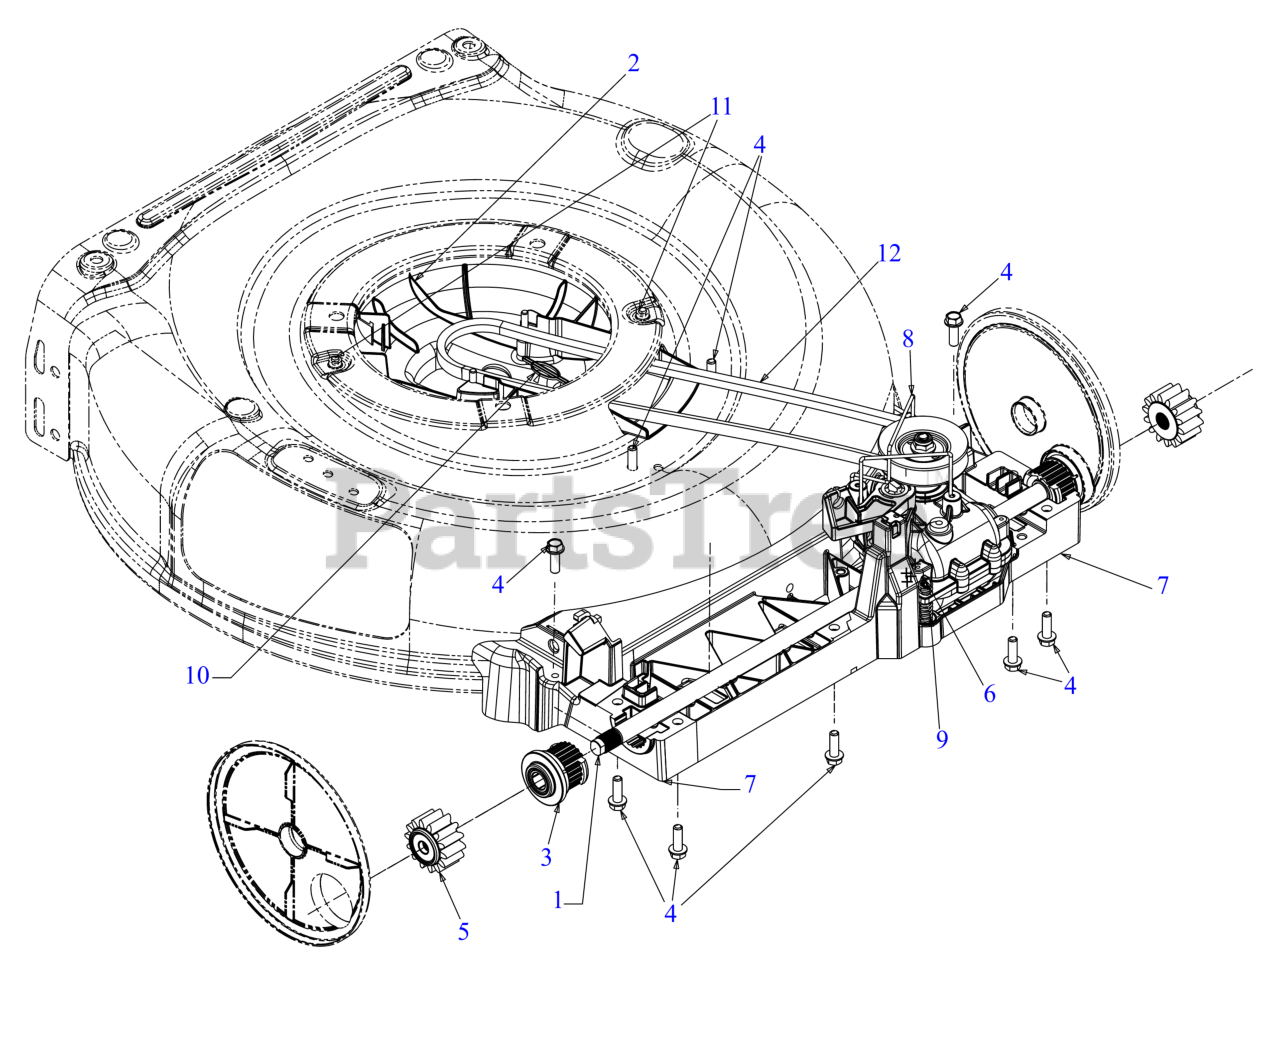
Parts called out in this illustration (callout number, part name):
1	TRANSMISSION ASSEMBLY
2	ENGINE BAFFLE ASSEMBLY
3	BEARING ASSEMBLY
4	SCREW 1/4-15 x .750
5	SPUR GEAR (14T) (RH)
6	SPRING COMPRESSION
7	TRAY (LOWER)
8	TRANSMISSION WIRE
9	COMPRESSION SPRING
11	SHOULDER SCREW 1/4-20 x .50
12	V-BELT 3L 34.18
